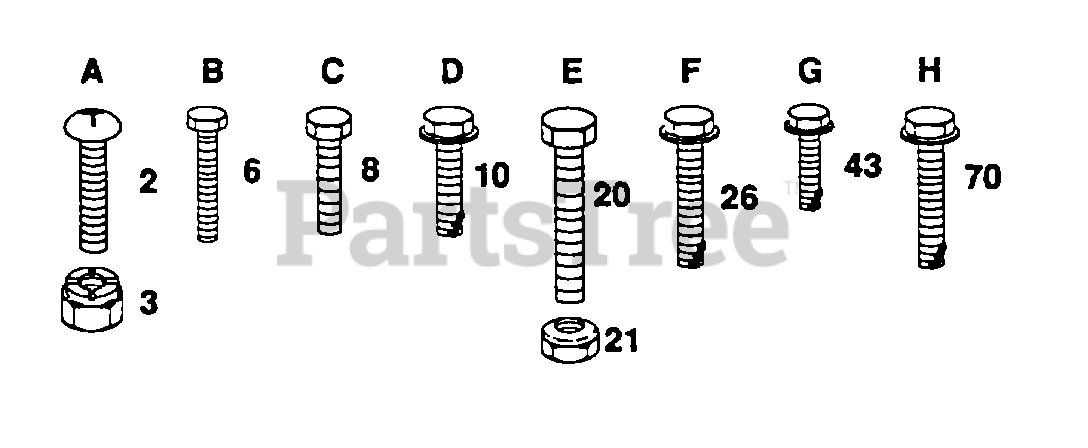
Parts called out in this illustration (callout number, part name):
2	SCREW
6	SCREW LT
10	SCREW LT
26	SCREW
43	SCREW LT
70	SCREW SPECIAL
